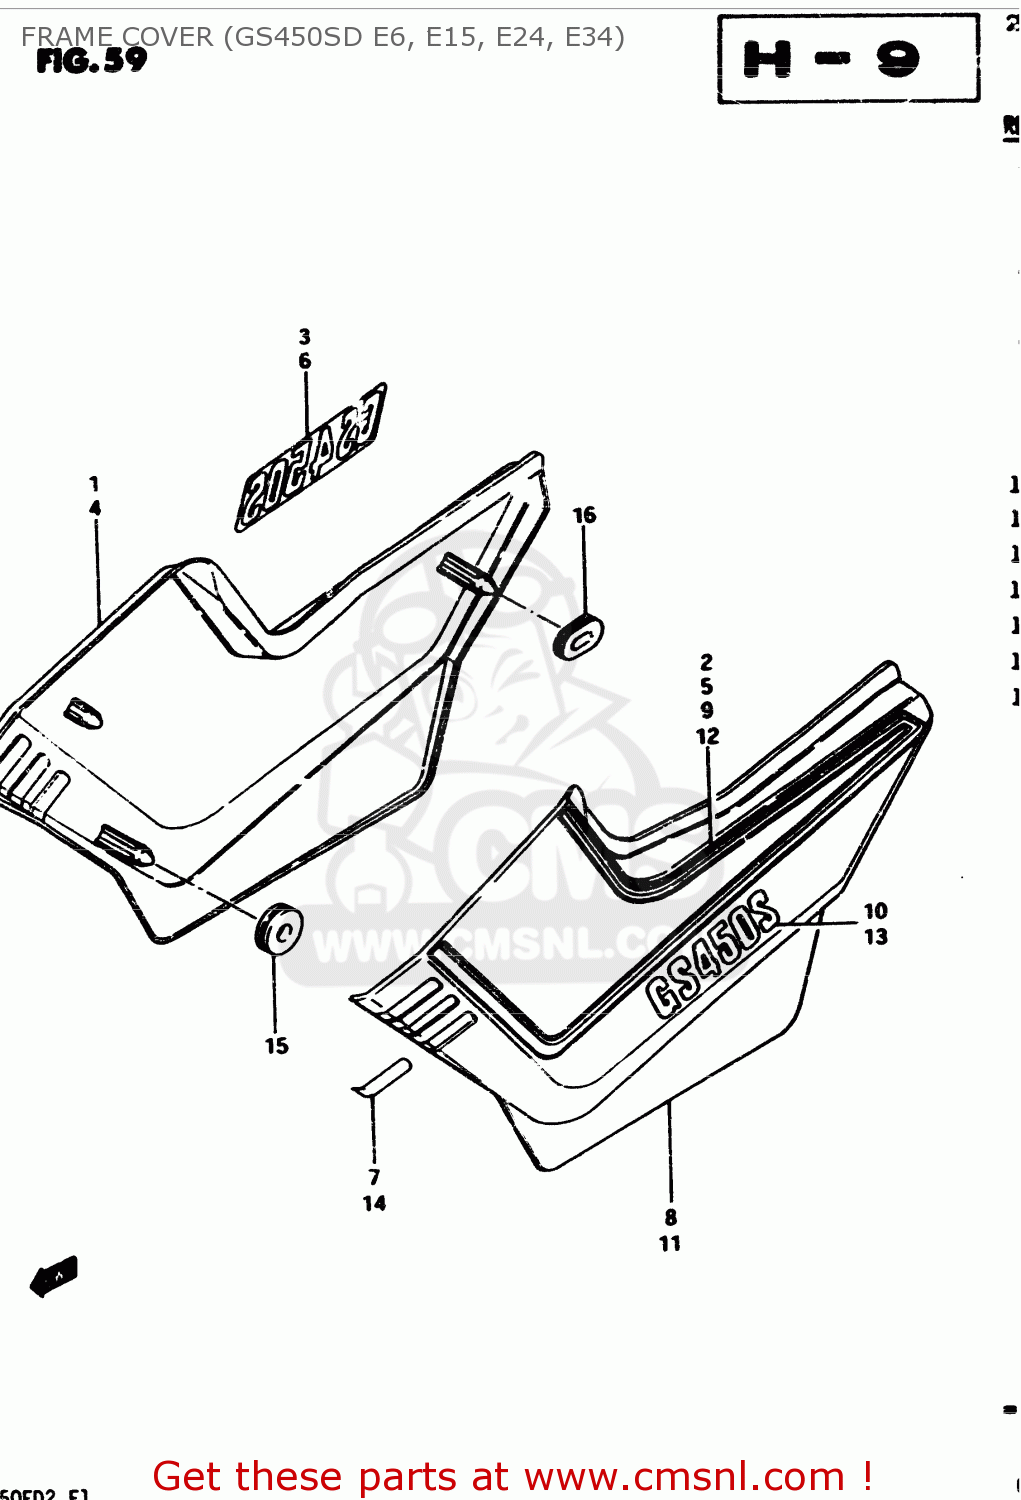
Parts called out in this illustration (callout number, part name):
1	COVER, FRAME RH
2	TAPE SET, FRAME COVER RH
3	EMBLEM, LH
4	COVER, FRAME RH
5	TAPE SET, FRAME COVER RH
6	EMBLEM, LH
7	LABEL,FRAME COVER DENT
8	COVER, FRAME LH
9	TAPE SET, FRAME COVER LH
10	EMBLEM, LH
11	COVER, FRAME LH
12	TAPE SET, FRAME COVER LH
13	EMBLEM, LH
14	LABEL,FRAME COVER
15	CUSHION
16	CUSHION
